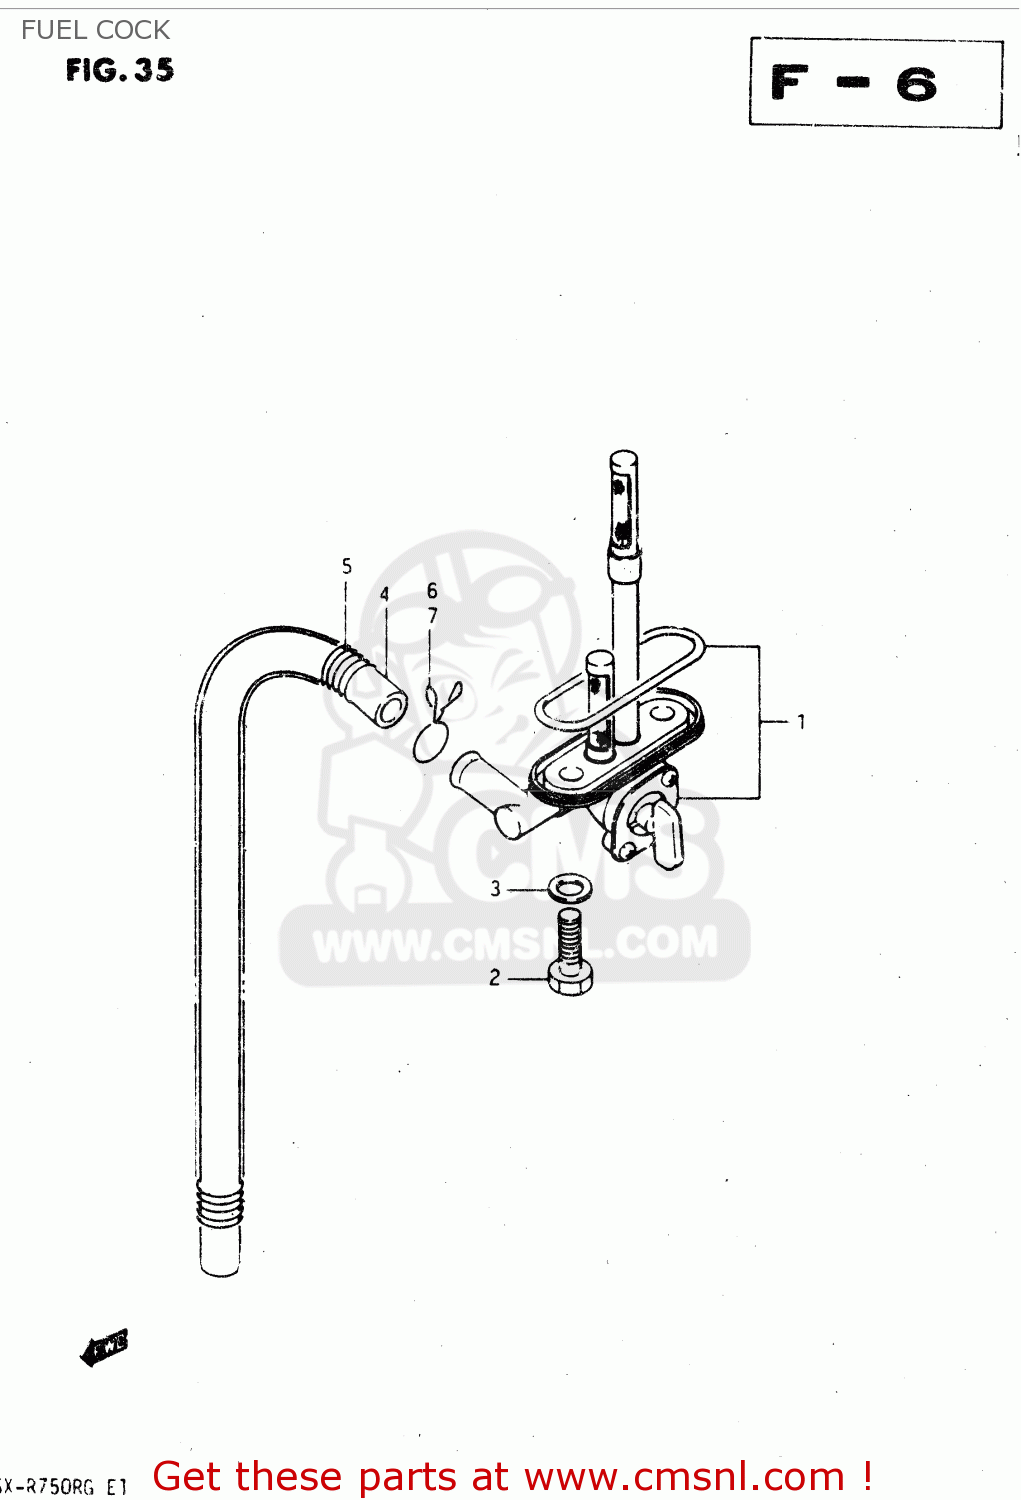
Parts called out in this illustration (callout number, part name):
1	COCK ASSY,FUEL
2	SCREW(6X20)
3	GASKET
4	HOSE
5	SPRING
6	(CA) CLIP
7	CLIP
